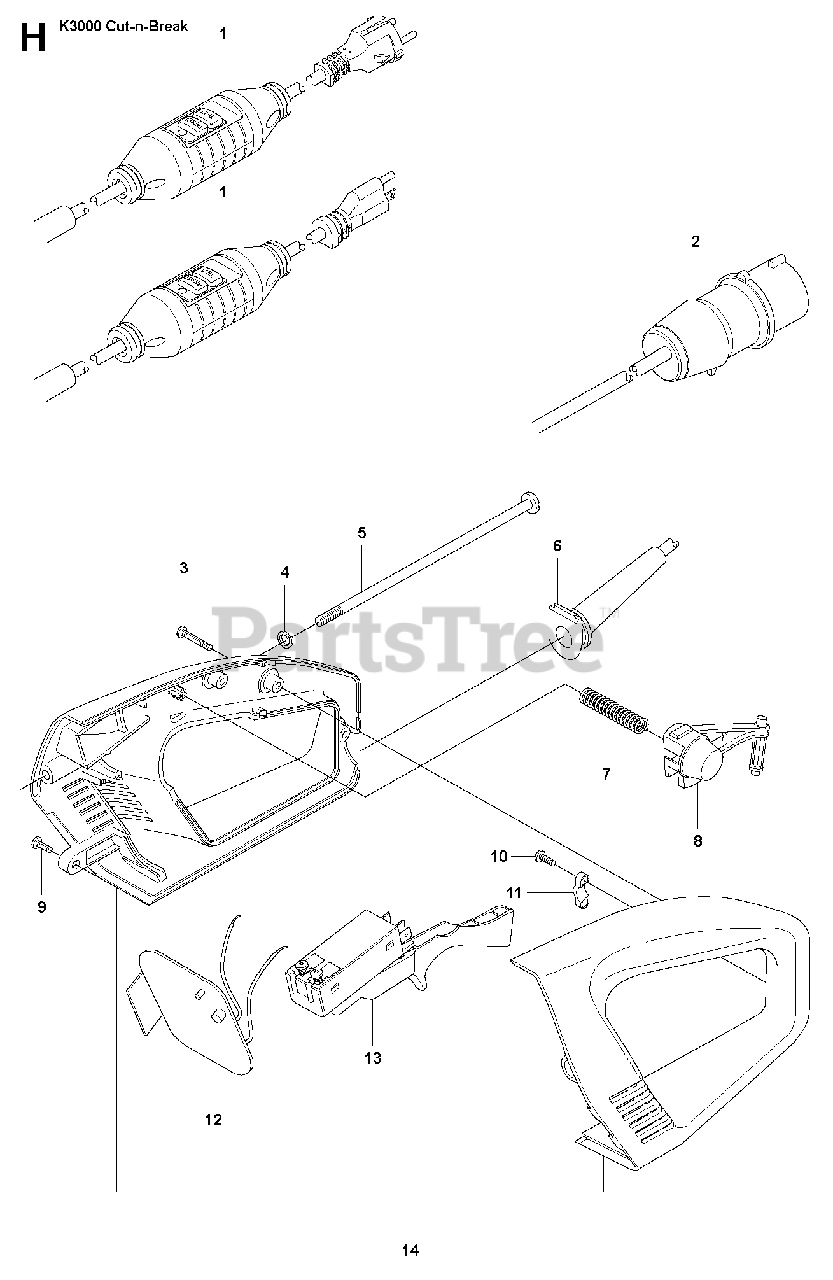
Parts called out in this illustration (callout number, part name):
1	CABLE110V JP, USA
4	SPRING WASHER
6	CABLE SLEEVE230V
7	SPRING
8	LOCKING BUTTON
9	SCREW CRPANM
12	ENGINE PROTECTION110V
12	ENGINE PROTECTION230V
14	HANDLE ASSY
